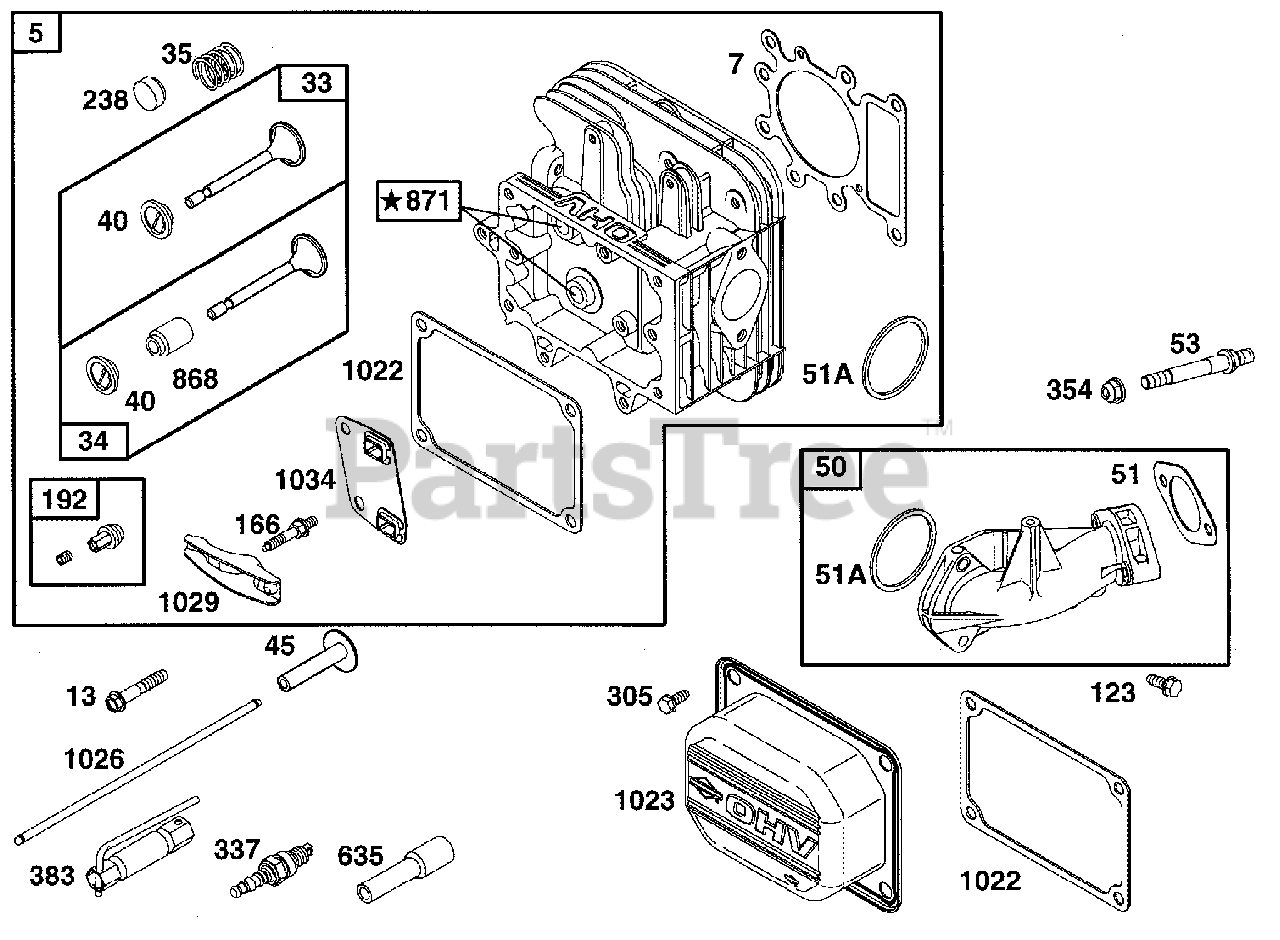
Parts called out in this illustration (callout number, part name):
5	Cylinder Head
7	Cylinder Head Gasket
13	Hex Screw
33	Exhaust Valve
34	Intake Valve
35	Valve Spring
40	Valve Retainer
45	Valve Tappet
50	Intake Manifold
51	Intake Gasket
51A	Seal-O-Ring
53	Carburetor Mounting Stud
123	Hex Screw
166	Rocker Arm Stud
192	Rocker Arm Adjuster
238	Valve Cap
305	Hex Screw
337	Spark Plug
354	Hex Nut
383	Spark Plug Wrench
635	Spark Plug Boot
868	Valve Seal
871	Guide Bushing
1022	Rocker Cover Gasket
1023	Rocker Cover
1026	Push Rod
1029	Rocker Arm
1034	Push Rod Guide
